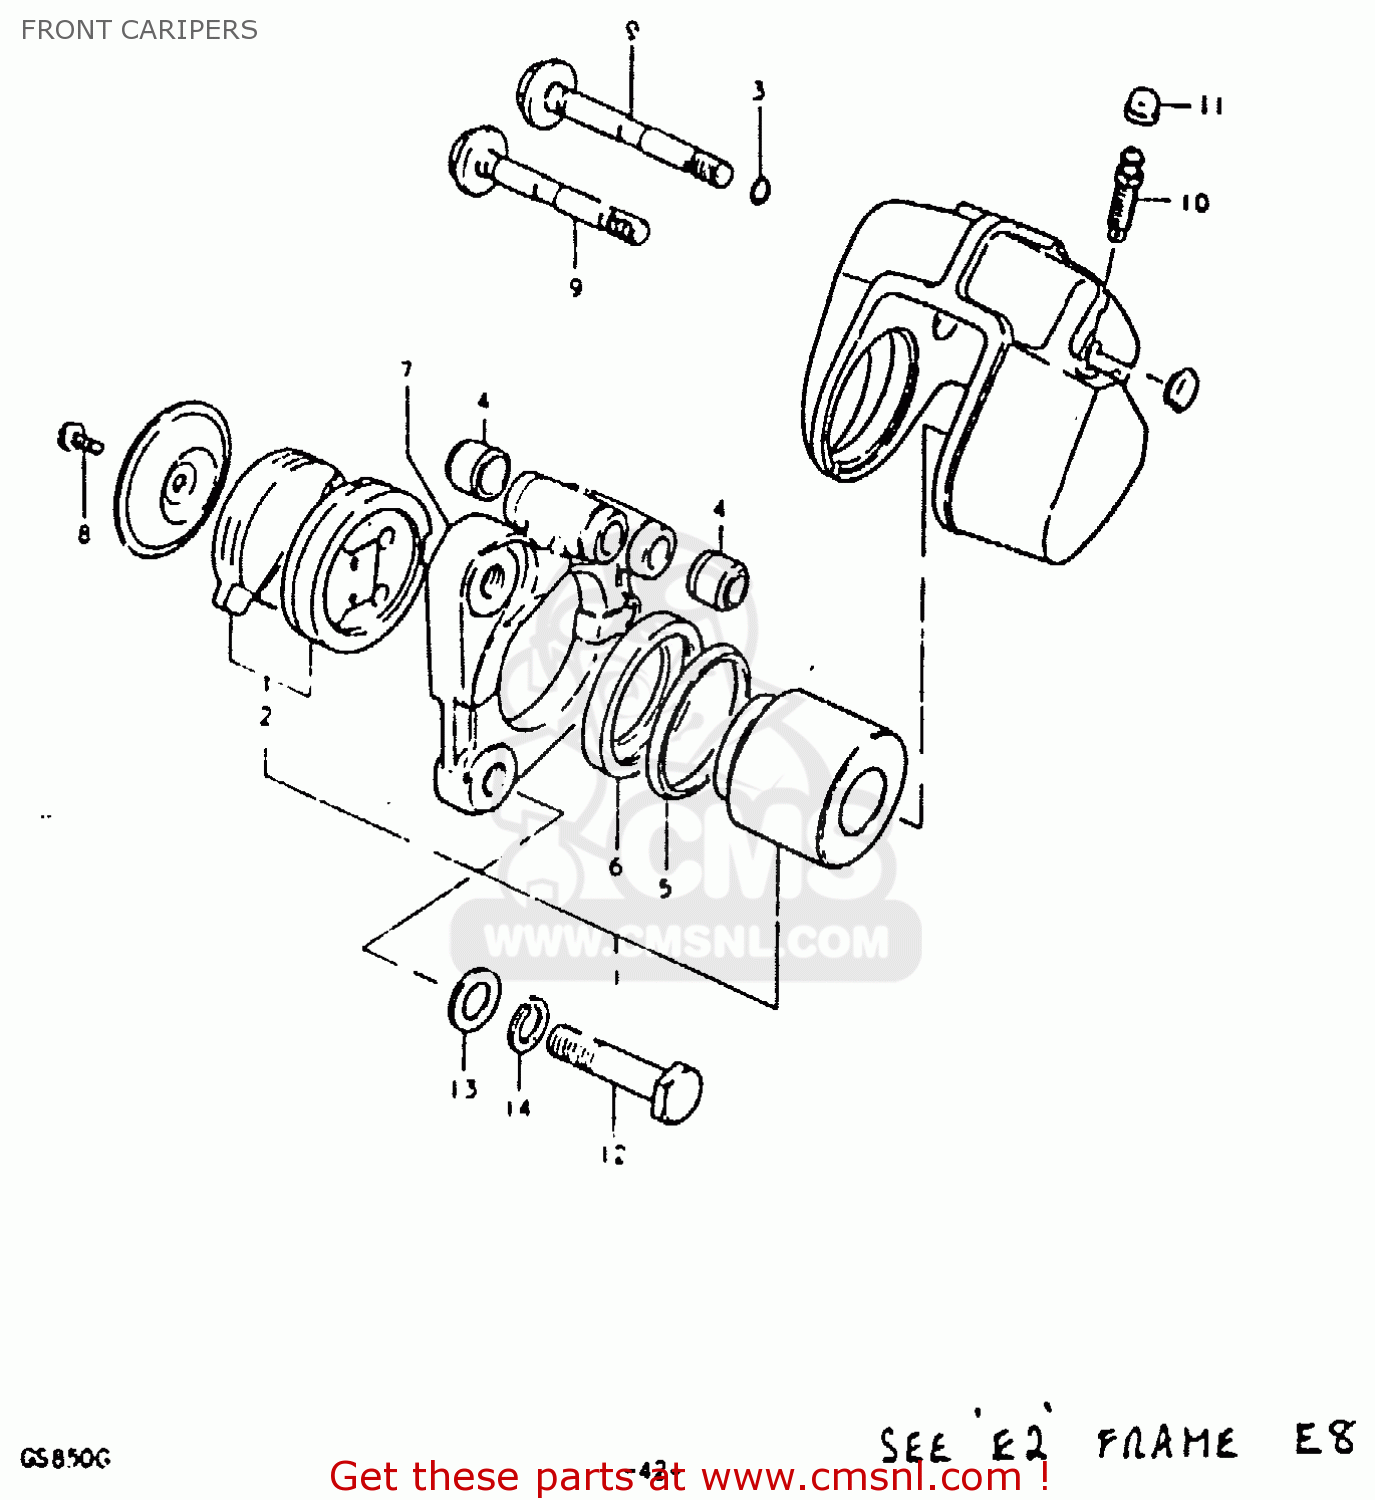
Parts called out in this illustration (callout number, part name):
1	PISTON & PAD SET
2	PAD SET (MCA)
3	O RING
4	COVER,AXLE DUST
5	SEAL,PISTON
6	BOOT,PISTON
7	HOLDER, CARIPERS RH
8	SCREW 6X12
9	AXLE,CALIPER
10	BLEEDER
11	CAP,BLEEDER PL
12	BOLT
13	WASHER
14	LOCK WASHER
